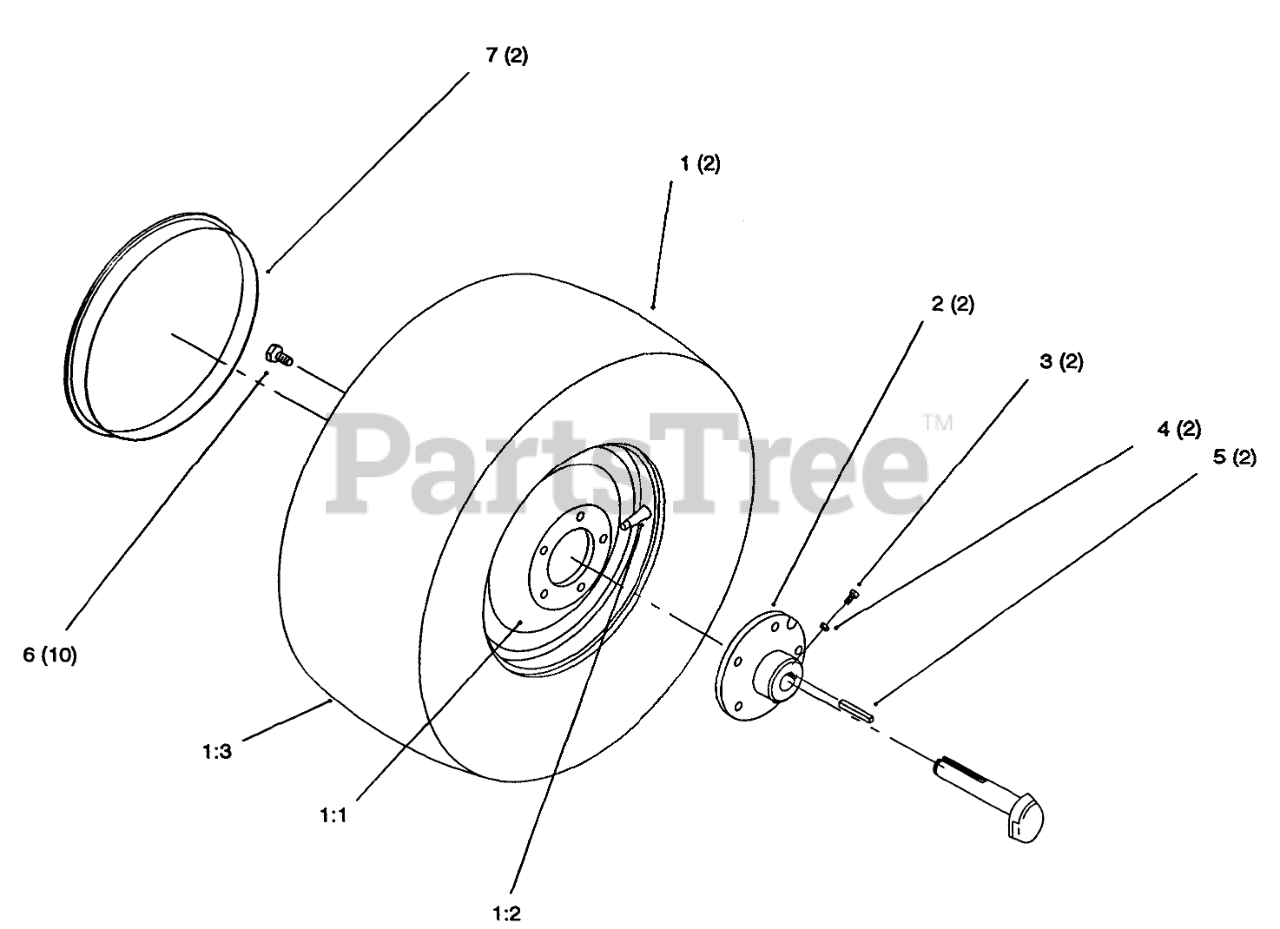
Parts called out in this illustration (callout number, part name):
1:1	WHEEL
1:2	VALVE
1:3	Tire (Only On: 72042, 72063, 72062, 72043)
1:3	Tire (Only On: 72083, 72103)
2	HUB-WHEEL
3	SCREW-SET, SQH
4	NUT-JAM
5	KEY-SQUARE
6	BOLT-LUG
7	Hubcap (Only On: 72083)
